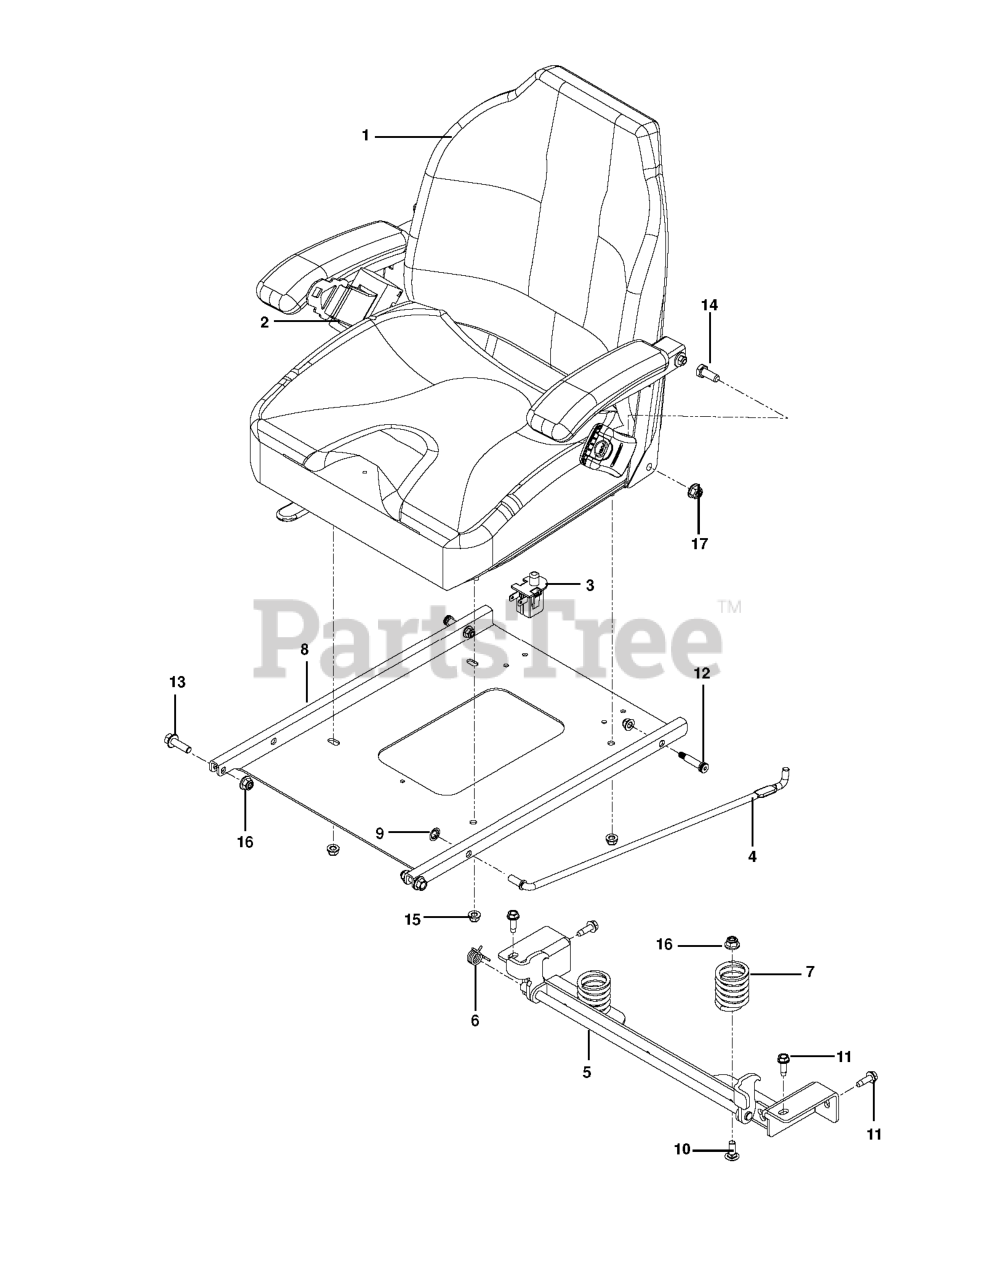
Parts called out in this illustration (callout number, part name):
1	SEAT.907.VINYL.HUSQVARNA
2	BELT, SEAT
3	SEAT SWITCH
5	LATCH.SEAT.BLACK
6	SPRING, TORSION
7	SPRING, SEAT
8	PAN, SEAT, BLACK
9	NUT 3/8 PALNUT RTNG BLK PHOS
10	RHSNB 3/8C X 1
11	RP BLT 5/16-18 X 1 THRD FORM D
12	BOLT, SHOULDER 3/8 X 1.25
13	HHFS 3/8-16 X 1.25 GD 5
14	HCS 7/16-14 X 1 GR 5 ZD
15	5/16-18 NYLOC FLANGE NUT
16	NUT 3/8-16 HEX FLG NYLOC ZD
17	NUT 7/16-14 HEX WHIZ LK
